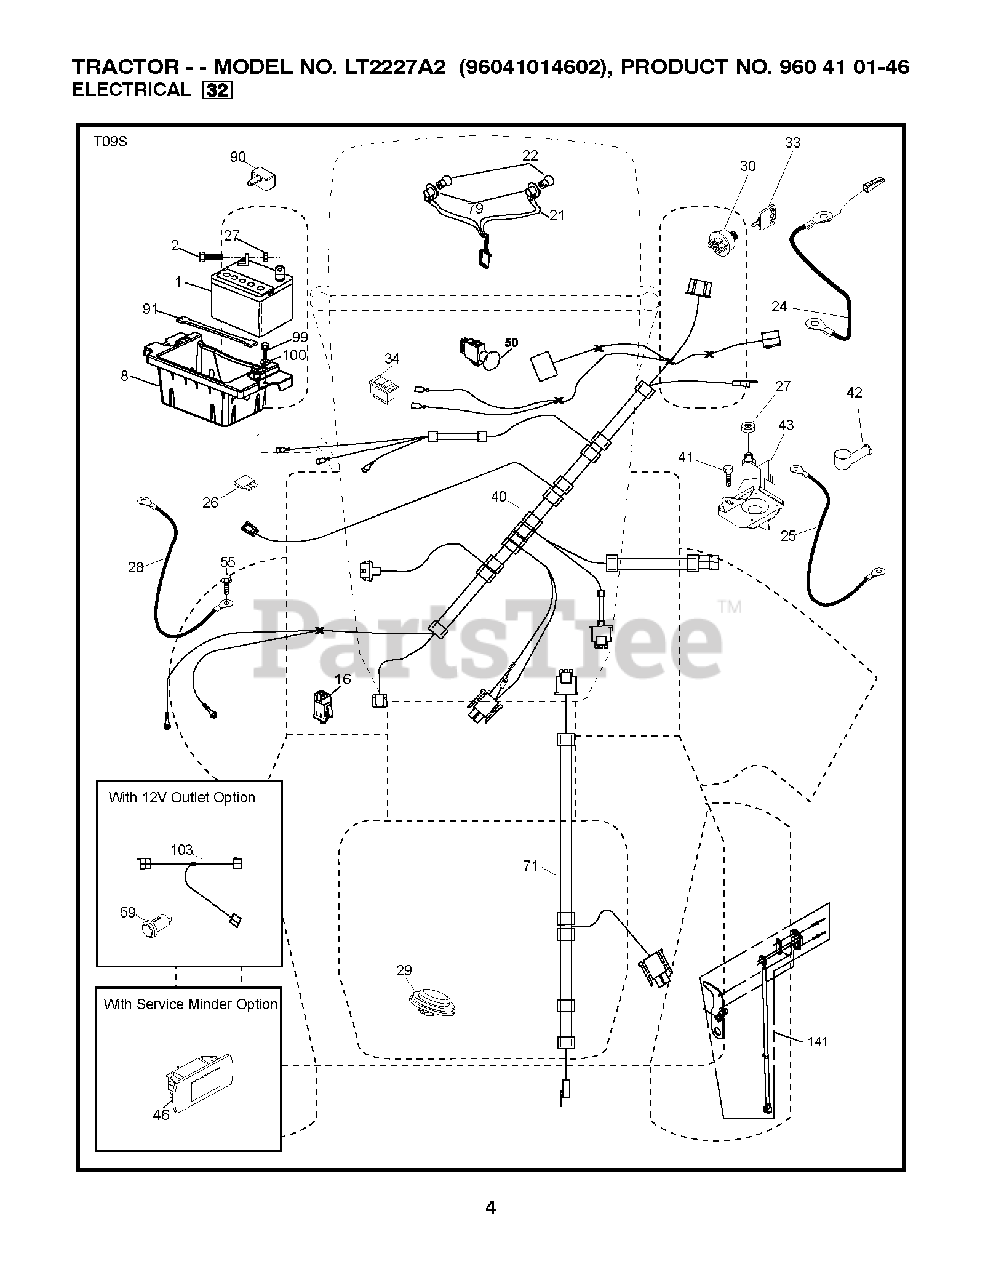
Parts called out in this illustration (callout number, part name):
1	REPL BY 532 12 38-99
8	BOX.BATTERY.MOUNT.FRONT.LT
16	SWITCH INTERLOOK PUSH-IN
21	HARNESS.LIGHT W/4152J BULBS
22	LIGHTBULB
24	CABLE.BATT.POS.WIRE.TG.DA SOL
25	CABLE.STARTER.6G.BL/RED.17.5
26	FUSE 20AMP
27	NUT
28	CABLE GROUND 6 GA 21" 90T BLK
29	SWITCH.SEAT.DELTA.OPC.
30	SWITCH.IGN.DELTA.W.LGH.ROS
33	KEY.CHAIN.BLISTER.PACK.GEN.USA
34	SWITCH LT
40	HARNESS.IGN.DASH.HUQ/P
41	SCREW
42	TERMINAL COVER
43	SOLENOID.W/BRASS.PLUNG
46	GUAGE.SRVCMNDR.HRMTR.
50	PTO SWITCH
55	SCREW 5/16"
71	HARNESS-CHASSIS SUB
79	BULB HOLDER ASM.
90	COVER.TERMINAL.BATTERY
91	STRAP, BATTERY MOUNT
99	SCREW HEXWSHR 1/4-20X3/4
141	KIT.G700/G730.ROS.SERV(71750)
